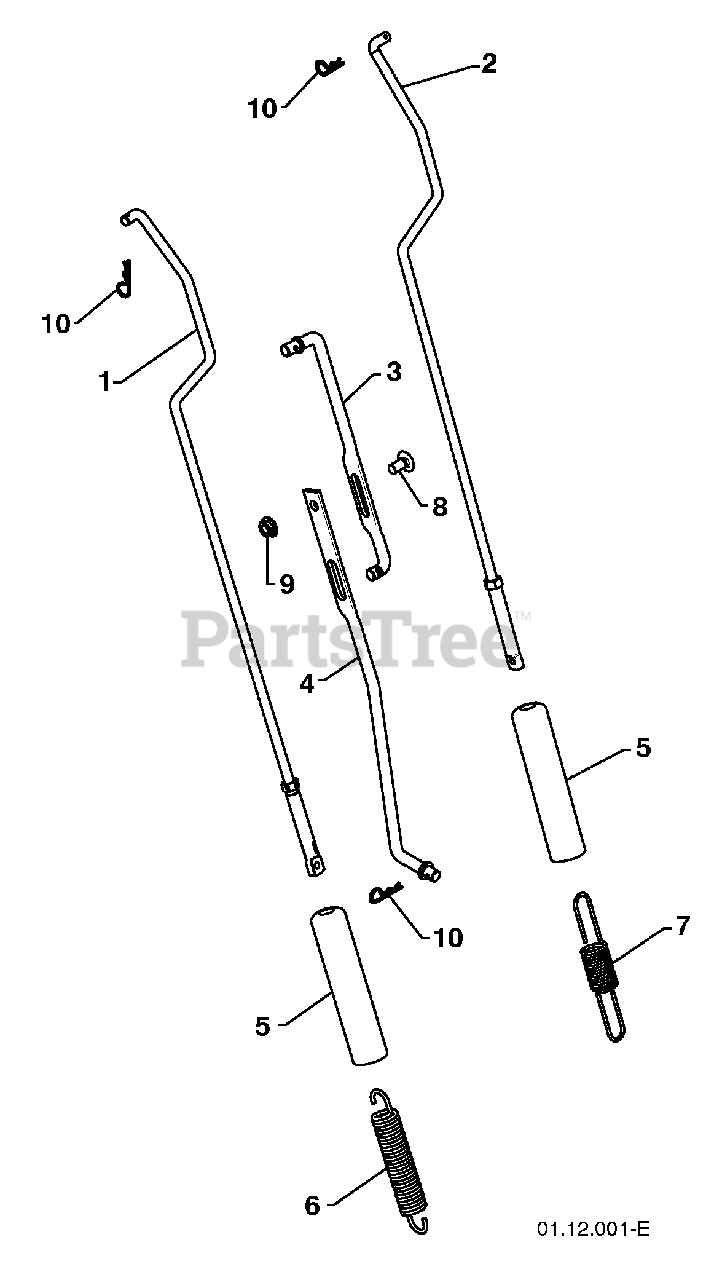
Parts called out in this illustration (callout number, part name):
1	IMPELLER ROD
2	TRACTION ROD
3	SHIFTER ROD TOP
4	SHIFTER ROD BOTTOM
5	SPRING SLEEVE
6	IMPELLER SPRING
7	TRACTION SPRING
8	CARRIAGE BOLT 5/16-18 X .625
9	NUT 5/16-18
10	RETAINER
